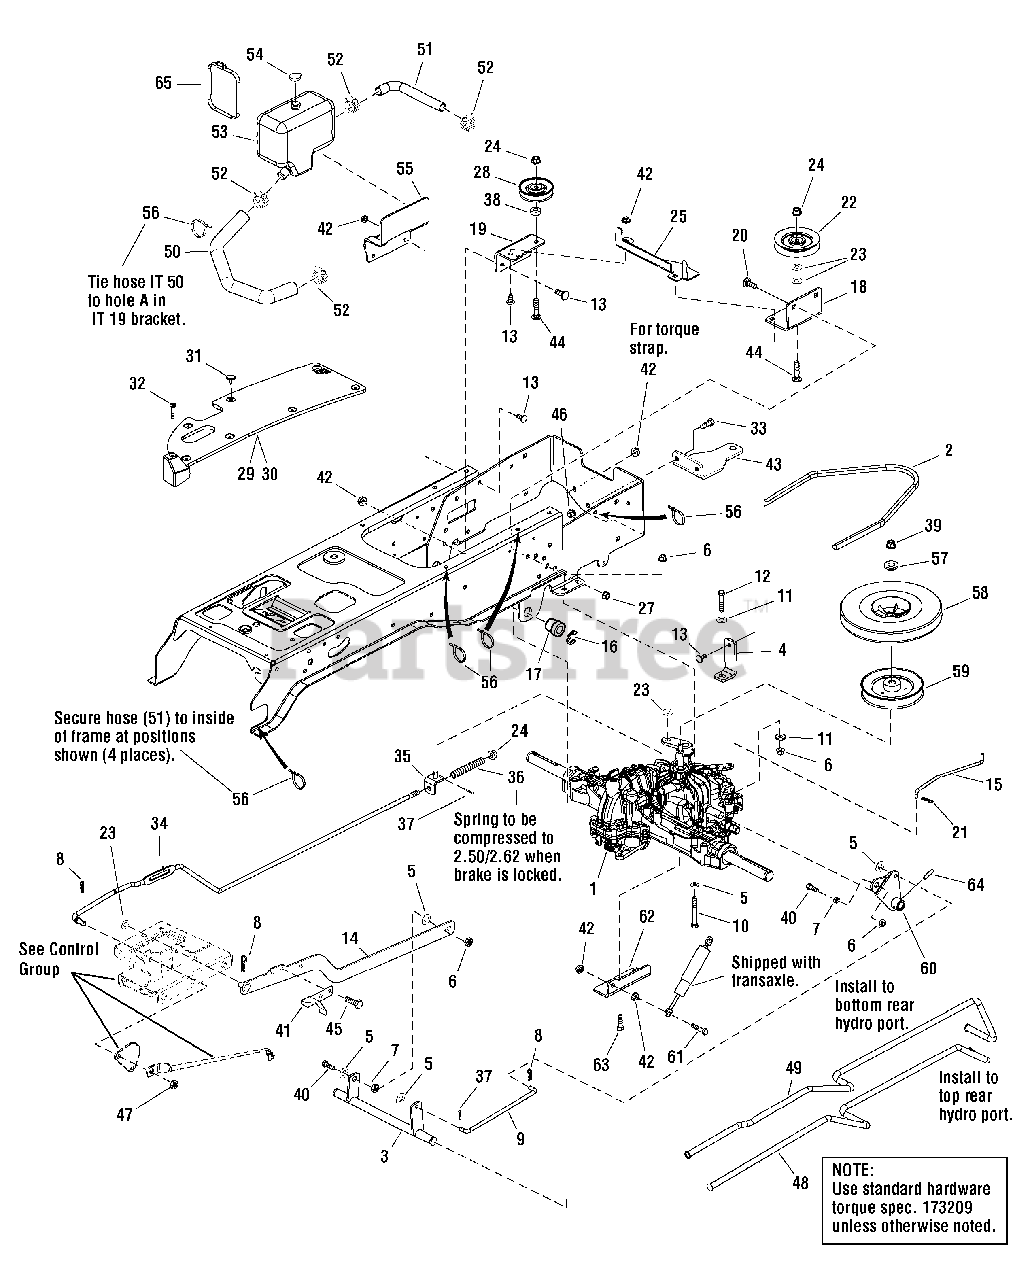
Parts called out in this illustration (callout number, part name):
1	TRANSMISSION ASSEMBLY, Tuff Torq K664
2	V-BELT, 117.0" EL HA
3	SHAFT & ARMS ASSEMBLY, Control
4	STRAP. Torque
5	WASHER, 5/16
6	NUT, Hex, CON, Lock, 5/16-18
7	SPACER, Powered Metal
8	PIN, Quick
9	ROD, Control
10	CAPSCREW, Hex Head, 5/16-18 x 2-3/4 G5
11	WASHER, 5/16
12	CAPSCREW, Hex Head 5/16-18 x 2 G5
13	CARRIAGE BOLT, 5/16-18 x 3/4 G5
14	ARM & PIN ASSEMBLY, Speed Control
15	ROD, Free Wheel
16	RING, E Retaining
17	BUSHING, Nylon
18	SUPPORT, Transmission, LH
19	SUPPORT, Transmission, RH
20	CARRIAGE BOLT, 3/8-16 x 1 G5
21	CLIP, Hair Pin Spring
22	PULLEY, Idler, 4 in.
23	WASHER, 3/8
24	NUT, Hex Flange 3/8-16 ESNA
25	BRACKET, Chute Locator
26	WASHER, Flat 3/8
27	NUT, Lock, KEPS, 3/8-16
28	PULLEY, V Idler
29	PAD, Footrest, RH Black Vinyl Textured
30	PAD, Footrest with Differential Lock, LH Black Vinyl Texture
31	FASTENER, Panel 3/4 Head
32	SCREW, Pnhd Torx tt, 1/4-20 x 1.25
33	CAPSCREW, Hex, 3/8-16 x 1.0
34	ROD, Brake
35	BRAKE, Bracket Assembly
36	SPRING, Compression
37	PIN, Cotter
38	BOLT, Carriage, 3/8-16 x 2
39	NUT, Flange, Nylock, M10
40	CAPSCREW, Hex Head, 5/16-18 x 1 G5
41	ACTUATOR, Switch
42	NUT, Hex Keps Conical Washer, 5/16-18
43	DRAWBAR
44	CARRIAGE BOLT, 3/8-16 x 1-3/4 G5
45	CAPSCREW, Hex Washer Head Taptite, 5/16-18 x 1/2
46	NUT, Hex Flange, 3/8-16 Whiz Lock Large
47	WASHER, 3/8
48	TUBE, Hydro, Front-Outside
49	TUBE, Hydro, Rear-Inside
50	HOSE, Tank
51	HOSE, Return
52	CLAMP, Hose
53	TANK, Reservoir
54	CAP, Tank
55	BRACKET, Tank Support
56	TIE, Wire
57	SPACER, Fan
58	FAN, 9
59	PULLEY ASSEMBLY
60	ARM ASSEMBLY, Control
61	CAPSCREW, Hex 5/16-18 x 1.50
62	BRACKET, Dampener, MTG
63	CAPSCREW, THD Cut, M8, 1.25 x 30
64	PIN, Drive
65	WIRE, Tie
66	CLAMP, Worm Drive
